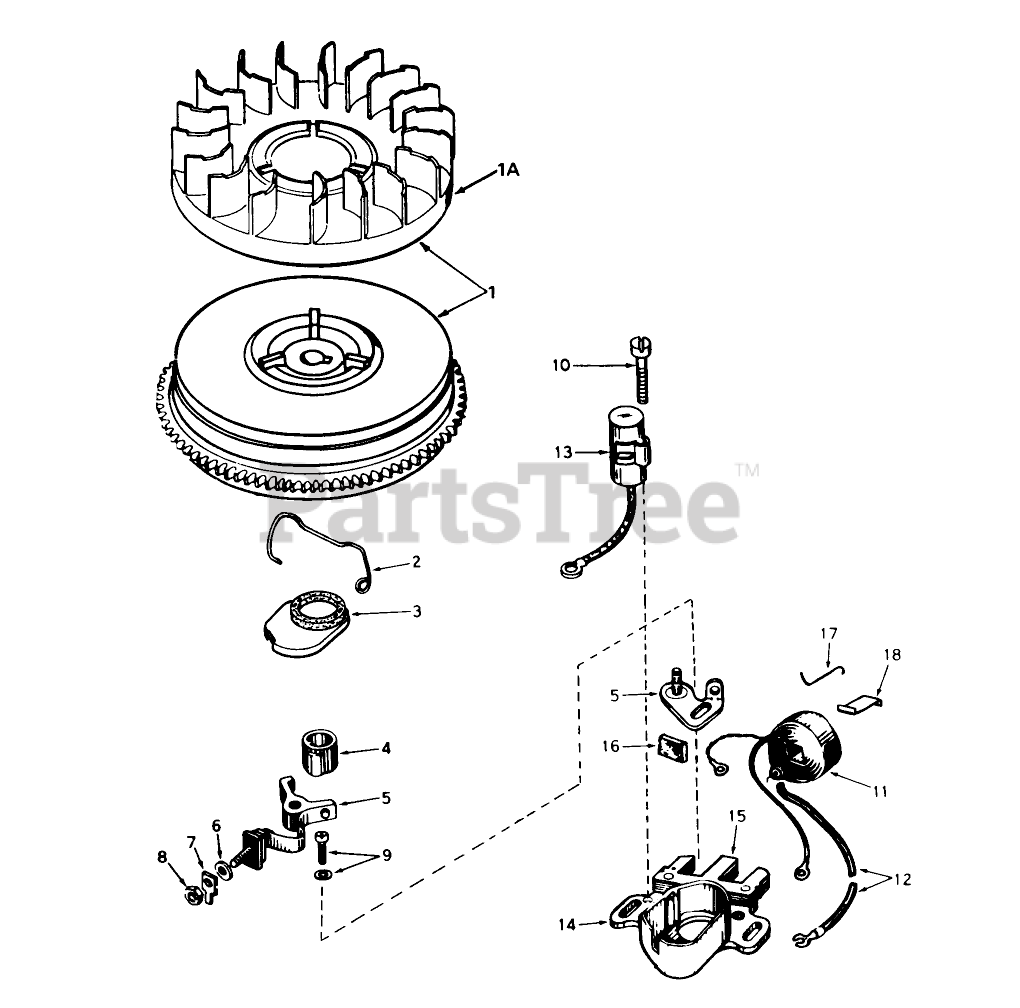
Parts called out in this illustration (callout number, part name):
1	Flywheel (Incl. No.1A)
2	Spring Breaker Box
3	Cover Gasket Assy.
4	Cam-Breaker
5	Breaker Assy.
6	Washer
7	Terminal, Ground
8	DECAL
9	Breaker Screw
10	Condenser Screw
11	Coil Assy. (Incl. No. 12)
12	Wire, Lead
13	Condenser
14	Core Plate
15	Stator Assy., (Incl. Nos. 2, 3, 5 thru 14 16 thru 19)
16	Felt,Cam Wiper
17	Clip, Coil
18	Spring Coil Wedge
